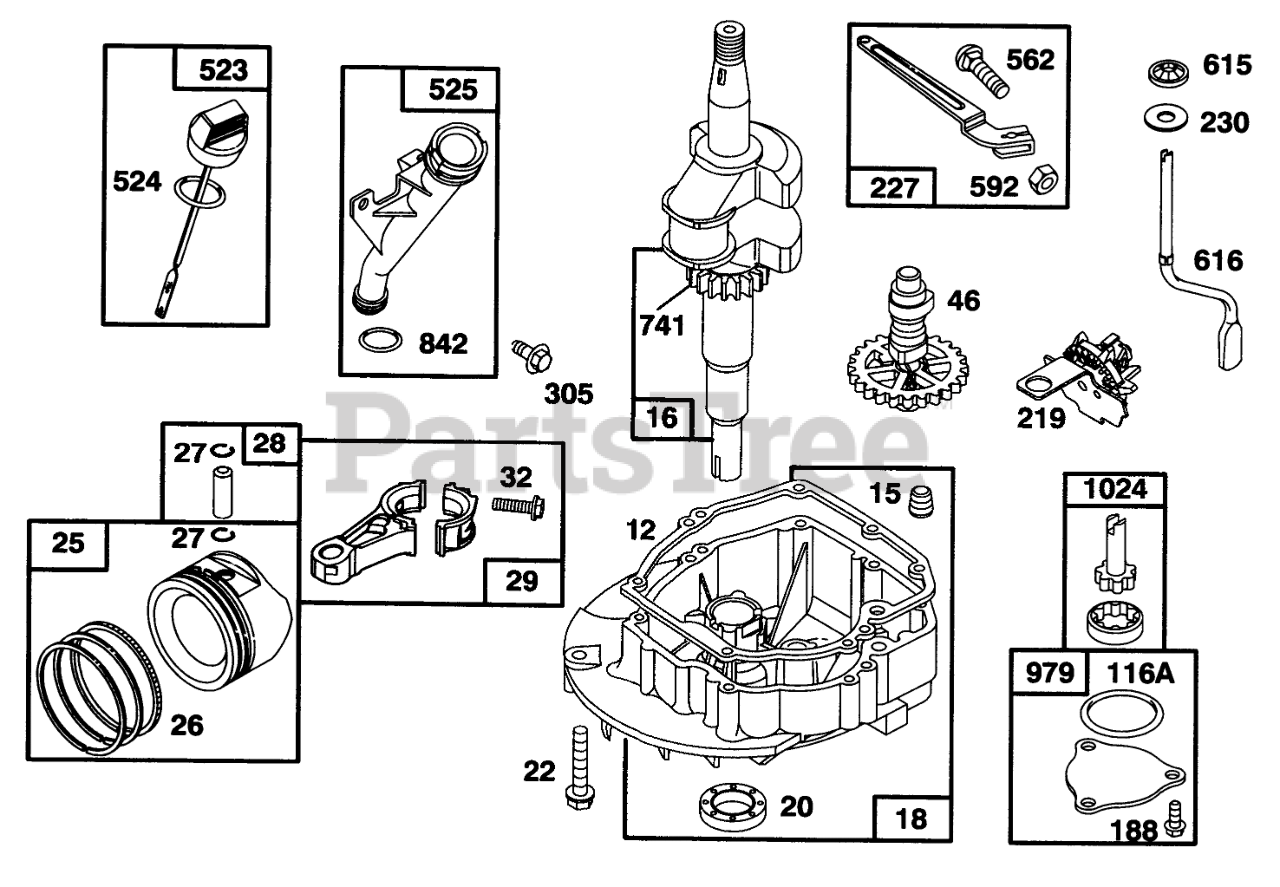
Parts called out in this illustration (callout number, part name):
12	ENGINE BASE GASKET
15	PLUG - PIPE
16	CRANKSHAFT
18	ENGINE SUMP
20	SEAL-OIL
22	SCREW - ENGINE BASE
25	STD PISTON ASSEMBLY
26	STD RING SET
27	PISTON PIN LOCK
28	PIN ASM - PISTON
29	CONNECTING ROD
32	SCREW - CONNECTING ROD
46	CAM GEAR
116A	O RING SEAL
188	SCREW - HEX HEAD
219	GOVERNOR/OIL SLINGER
227	GOVERNOR LEVER ASSEMBLY
230	WASHER
305	SCREW - HEX HEAD
523	DIPSTICK-OIL
524	O-RING
525	OIL FILLER TUBE
562	BOLT - GOVERNOR LEVER
592	NUT - HEX
615	FASTENER
616	GOVERNOR CRANK
741	TIMING GEAR
842	O-RING
979	OIL PUMP COVER
1024	OIL PUMP
